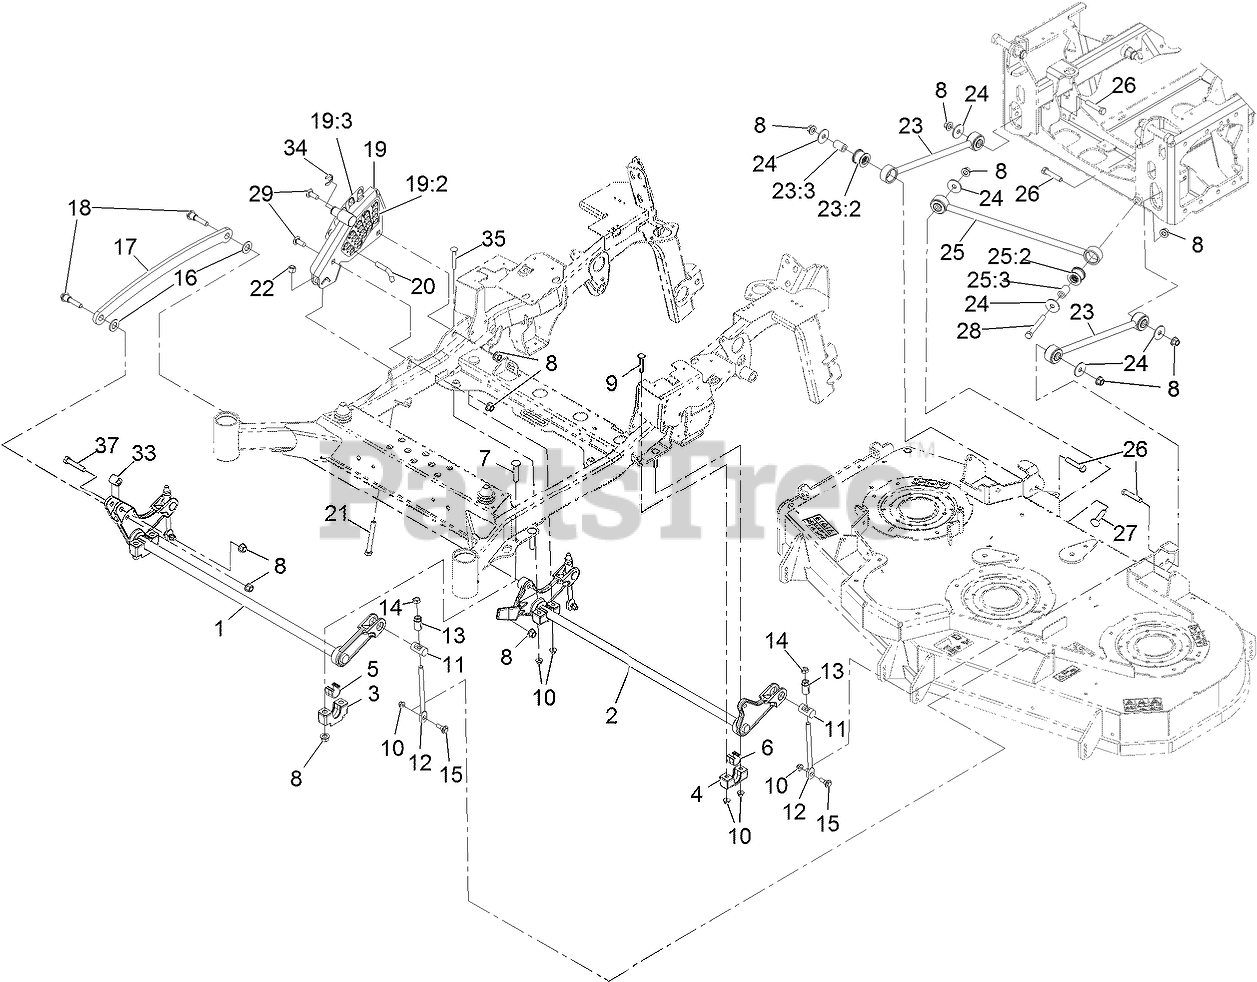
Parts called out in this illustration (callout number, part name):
1	DECKLIFT-FRONT
2	LIFT-DECK, REAR
3	SUPPORT-CROSS SHAFT, BEARING
4	SUPPORT-CROSS SHAFT, BEARING REAR
5	BEARING-CROSS SHAFT, FRON
6	BEARING-CROSS SHAFT, REAR
7	Bolt-Carriage 1/2-13 X 2 1/2 Spl Neck
8	Nut-Lock 1/2-13
9	Bolt-Carriage 3/8-16 X 2 1/4
10	NUT-HF, NI
11	TRUNNION
12	LINK-ADJUSTER, DECK LIFT
13	ADJUSTER-LIFT, DECK
14	NUT-JAM
15	SCREW-SHOULDER, HHF
16	WASHER-FLAT
17	LINK-LIFT, DECK
18	SCREW-HHF, SHOULDER
19	HOC ASM
19:2	DECAL-HEIGHT OF CUT
19:3	DECAL-HEIGHT OF CUT, OUTER
20	PIN-HOC
21	BOLT-TAP
22	NUT-LOCK, NI
23	DECK STRUT ASM
23:2	BUSHING-SUSPENSION, RUBBER
24	WASHER-THRUST
25	PANHARD ROD ASM
25:2	BUSHING-SUSPENSION, RUBBER
26	SCREW-HH
27	SCREW-CARR
28	SCREW-HH
29	SCREW-CARR, SHORT NECK
33	SPACER-PIVOT
34	RING-RETAINING
35	SCREW-CARR
37	SCREW-HH
